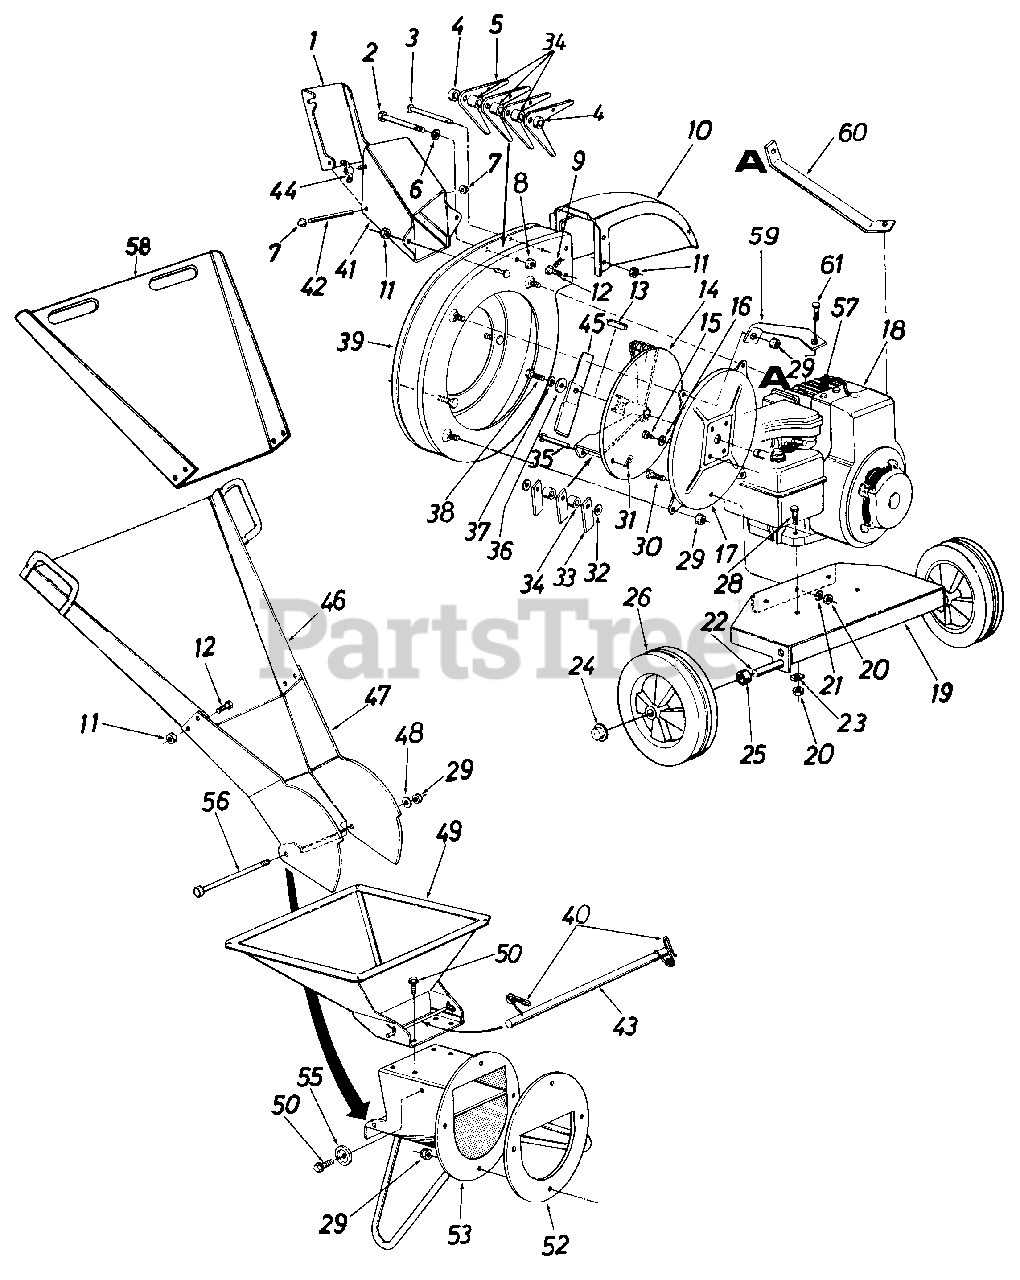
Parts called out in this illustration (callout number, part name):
1	Door Chip It
2	Hex Bolt 1/2-2C x 4.50" Lg t
4	Flail Spacer 7/32" Lg.
5	Cutting Finger
6	L.-Wash. 1/2" I.D.
7	Palnut 3/16" Dia.
8	Hex Jam Nut 1/2-20 Thd.
9	Cotter Pin 3/32" Dia. x 3/4" Lg.
10	Chute Delfector
11	L.-Nut 1/4-20 Thd.
12	Hex Bolt 1/4-20 x .50" Lg.'
13	Sq. Key 4" x 2.00" Lg.
14	Impeller Assembly
15	Hex Bolt 5/16-24 x 314" Lg.
16	L.-Wash. 5/16" I.D.
17	Hopper to Engine Mtg. Plate
18	Engine
19	Engine Mounting Plate
20	Hex Nut 5/16-24 Thd.
21	L.-Wash. 5/16" I.D.
23	Special L.-Wash. 5/16" I.D.
26	Wheel Ass'y.-Comp. (White)
28	Hex Bolt 5/16-24 x 1.50" Lg.
29	Elastic Lock Nut 5/16-18 Thd.
30	Hex Bolt 5/16-24 x .62" Lg.
31	Cotter Pin 1/8" Dia. x 1.00" Lg.
32	Fl.-Wash. .531" I.D. x .937 O.D. x .09
33	Flail
34	Spacer 23/32" Lg.
35	Clevis Pin .50" Dia. x 3.0" Lg.
36	Fl.-Wash. .406" I.D. x 1.25" O.D. Hdn.
37	L.-Wash. 3/8" I.D. H.D.
38	Hex Bolt 3/8-24 x 2.0" Lg. H.T.
41	Chip-lt Guide Ass'y.
42	Hinge Pin
44	Wing Nut Elastic 1/4-20 Thd.
47	Lower Leaf Ramp Section
48	Fl.-Wash. 5/16" I.D.
49	Hopper Assembly
50	Hex Wash. Hd. Self-Tap Scr. 5/16-18 x .75" 4.
52	Back-Up Plate
53	Inlet Guide Assembly
55	Stop Washer
56	Hex Bolt 5/16-28 x 8.38" Lg.
57	Spark Plug Boot lOptional
60	Impeller Hsg. Support Brace-L.H.
61	Part of Engine
